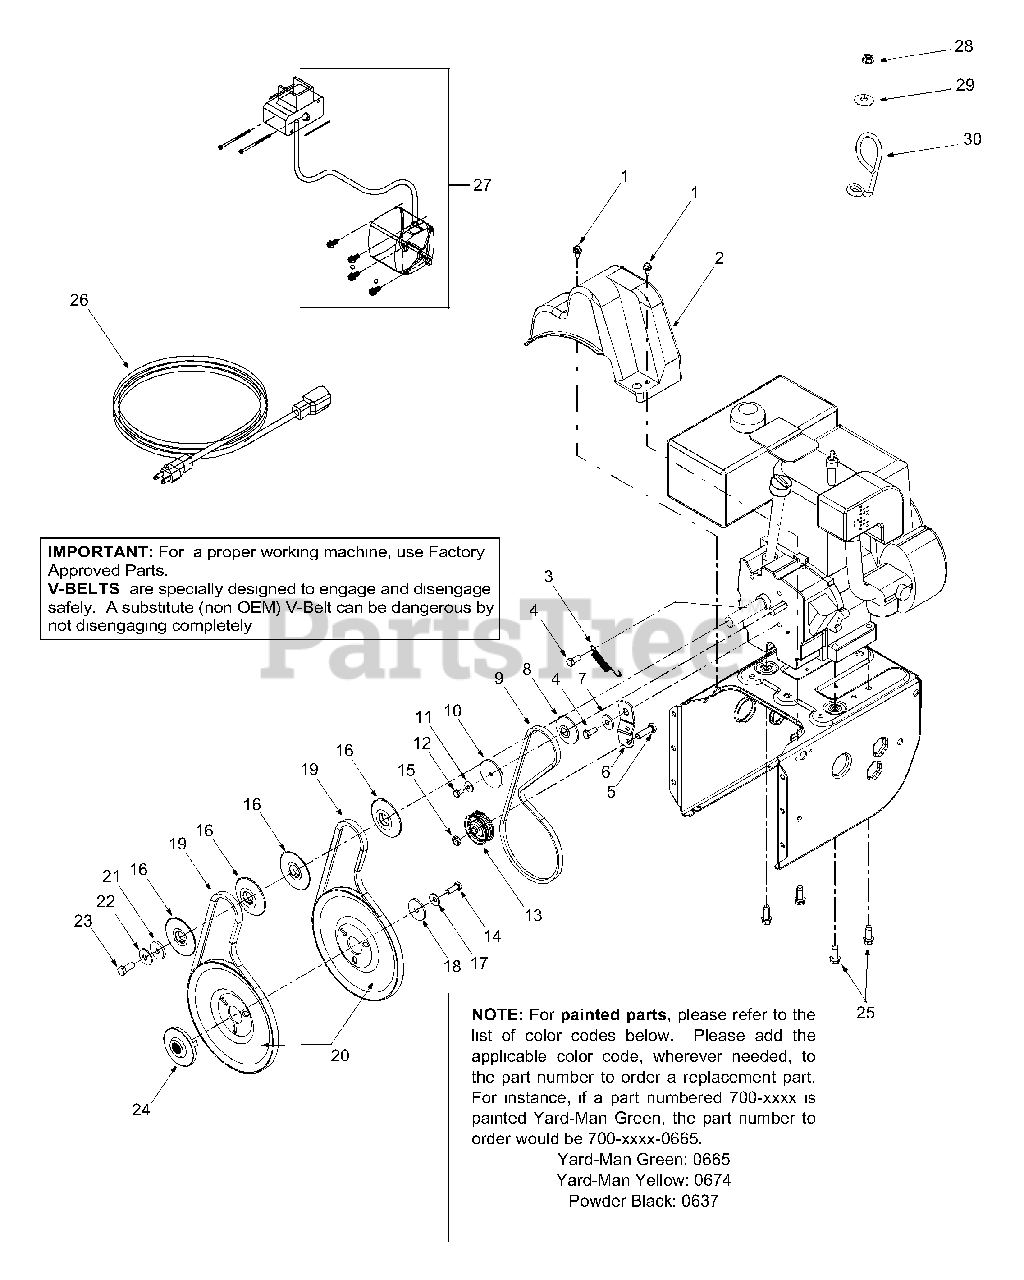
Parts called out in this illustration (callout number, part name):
1	Hex Washer Screw 1/4-20 x .625
2	Belt Cover
3	Extension Spring
4	Hex Screw 5/16-24 x .75
5	Hex Cap Screw 3/8-16 x 1.25
8	Pulley Half
9	V-Belt Half
10	Pulley
11	Bell Washer
12	Hex Cap Screw 1/4-28 x .50
13	Flat Idler
14	Lock Hex Cap Screw 5/16-24
15	Lock Jam Nut 3/8-16
16	Pulley Half
17	Bell Washer
18	Flat Washer
19	Belt
20	Auger Pulley
21	Flat Washer 3/8 x 1.25 OD
22	Bell Washer
23	Hex Cap Screw 3/8-24
24	Adapter Pulley
25	Hex Screw 3/8-16 x 1.0
26	Extension Cord
27	Electric Start Kit
28	Lock Nut, 1/4-20
29	Flat Washer, .28 x .74 x .063
30	Cable Guide
